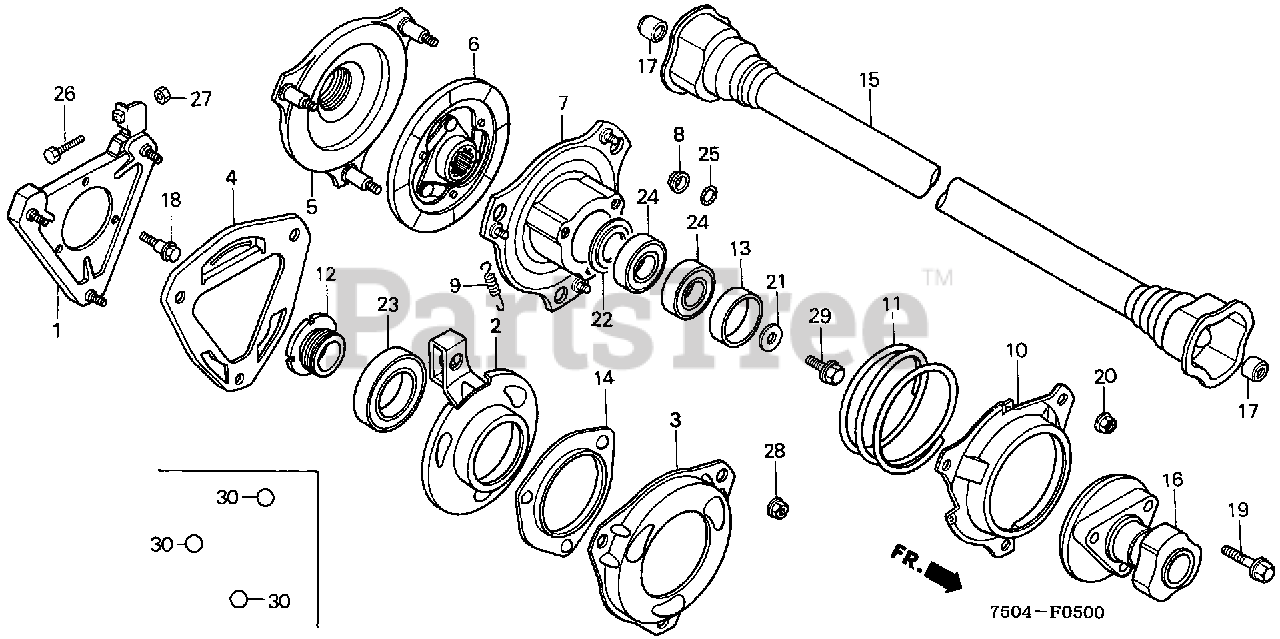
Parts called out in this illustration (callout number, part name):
1	HOUSING A, RR. CLUTCH
2	PLATE, BALL CONTROL
3	HOUSING B, RR. CLUTCH
4	PLATE, DUST SEAL
5	PLATE KIT, LIFTER
5	PLATE, LIFTER
6	PLATE, DRIVE
7	PLATE, PRESSURE
8	BUSH, RR. CLUTCH
9	SPRING, CLUTCH SETTING
10	COVER, CLUTCH
11	SPRING, CLUTCH (NOT AVAILABLE)
12	NUT, BEARING
14	RETAINER, BALL
15	SHAFT, PROPELLER
16	DAMPER A, PROPELLER SHAFT
17	BUSH, CENTERING
18	BOLT, SPECIAL (6X23)
19	BOLT, UBS (8X33)
20	NUT, U (6MM)
21	WASHER (8MM)
22	WASHER, SPECIAL
23	BEARING, RADIAL BALL (6908LLU)
23	BEARING, RADIAL BALL (6908)
24	BEARING, RADIAL BALL (6203)
25	O-RING (9.8X2.4)
26	BOLT, SPECIAL (6X25)
27	NUT, HEX. (6MM)
28	NUT, FLANGE (6MM)
28	NUT, DRIVEN SPROCKET (TOKAI)
29	BOLT, FLANGE (8X14)
